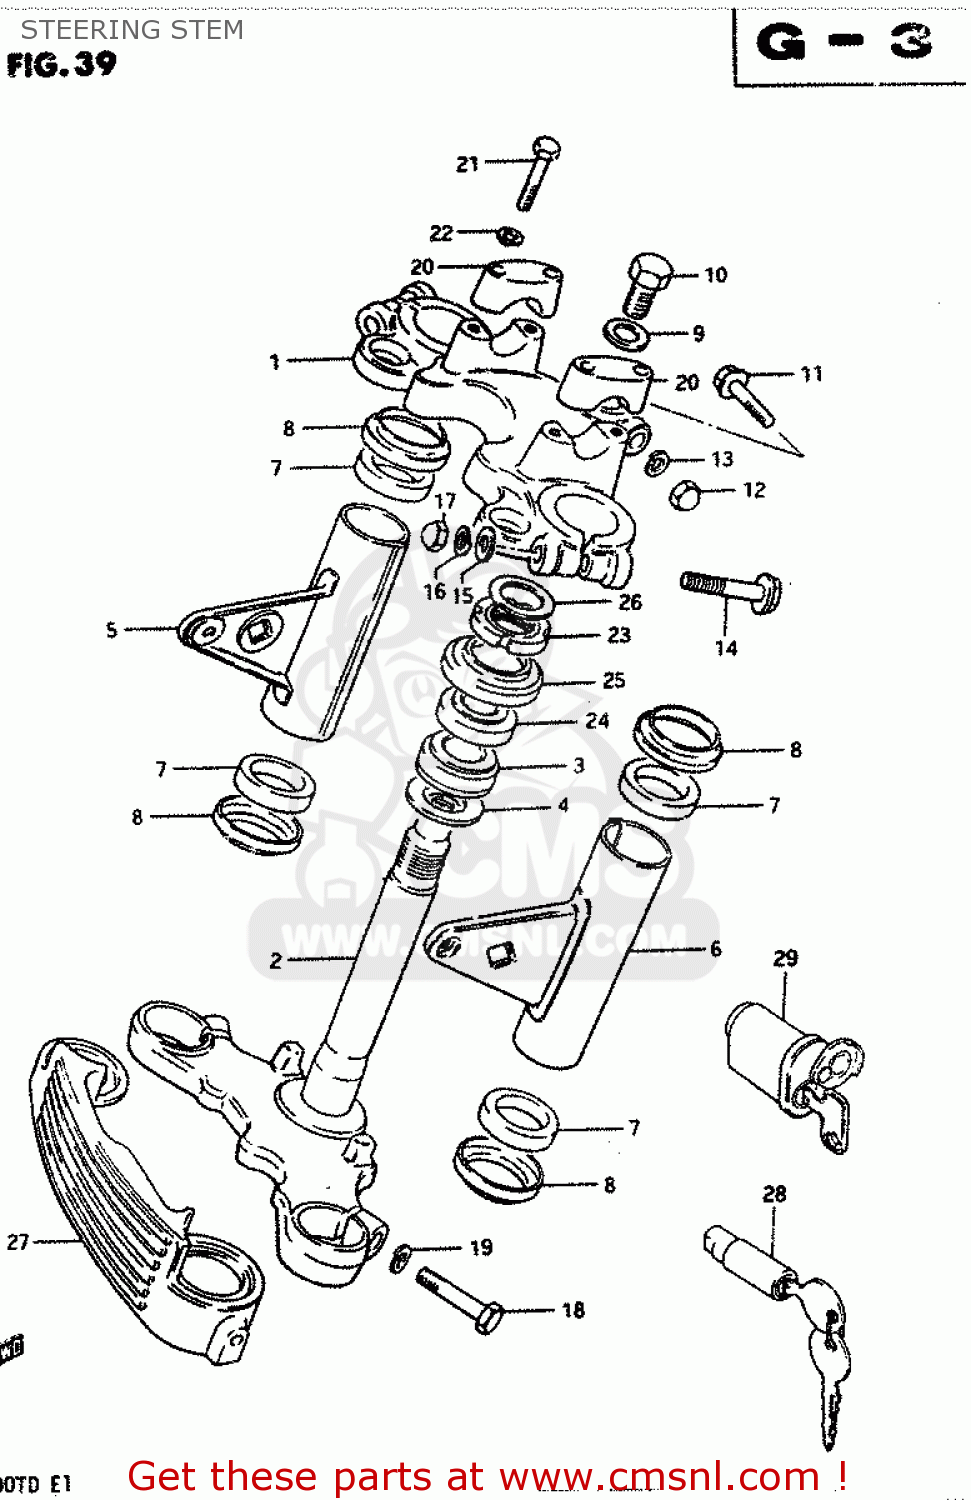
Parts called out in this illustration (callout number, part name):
1	HEAD,STEERING STEM
2	STEM,STEERING
3	BEARING
4	WASHER,THRUST
5	BRACKET,HEADLAMP,RIGHT
6	BRACKET,HEADLAMP,LEFT
7	CUSHION,HEADLAMP BRACKET
8	CAP,HEADLAMP BRACKET
9	WASHER
10	BOLT(12X20)
11	BOLT
12	NUT,M8X1.25X12
13	LOCK WASHER
14	BOLT 10X55
15	WASHER
16	LOCK WASHER
17	NUT
18	BOLT
19	LOCK WASHER
20	HOLDER,HANDLE UPR
21	BOLT
22	WASHER,LOCK,8.
23	NUT,STEERING STEM
24	TAPER,ROLLER BEARING
25	DUST SEAL,STEERING UPR
26	WASHER(18.5X24X1)
27	COVER,FRONT FORK
28	LOCK ASSEMBLY,STEERING (NEI
29	LOCK ASSY, STEERING (NEIMAN TYPE EXECUTE
